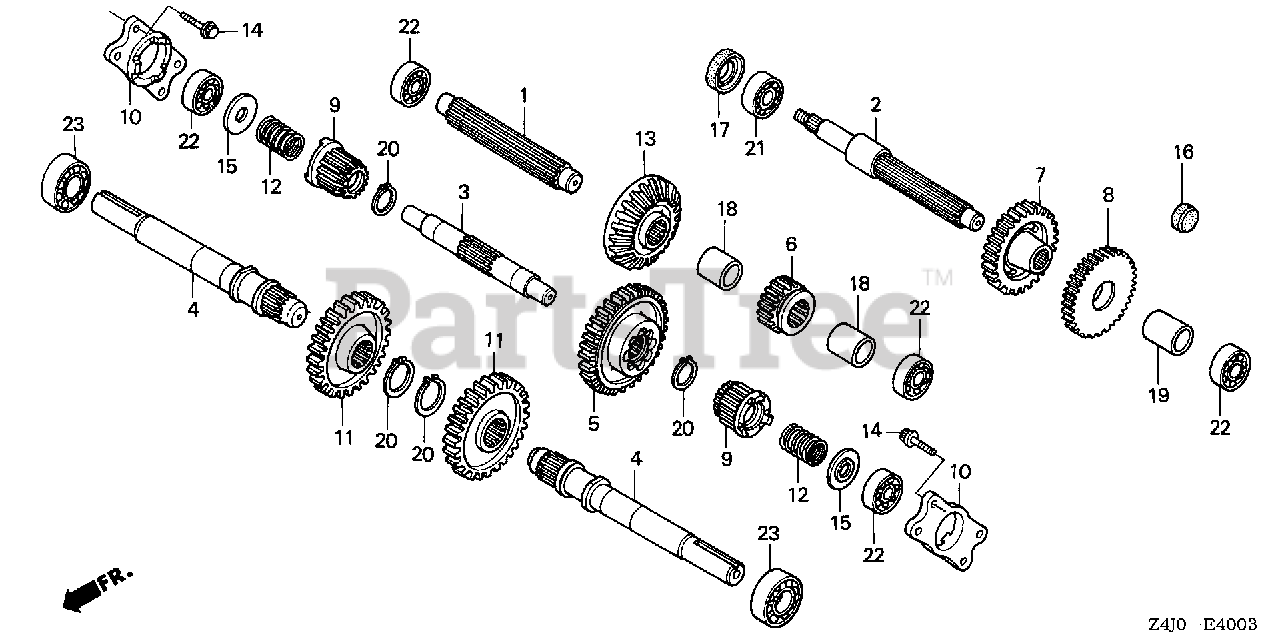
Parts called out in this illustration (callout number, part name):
1	SHAFT, INPUT
2	COUNTERSHAFT
3	SHAFT, SIDE CLUTCH
4	SHAFT, WHEEL
5	GEAR, SIDE CLUTCH DRIVE (49T)
6	GEAR, INPUT SHAFT CHANGE (19T)
7	GEAR, COUNTERSHAFT (36T)
8	GEAR, DRIVEN (42T)
9	GEAR, SIDE CLUTCH (16T)
10	CASE, SIDE CLUTCH BEARING
11	GEAR, FINAL (35T)
12	SPRING, SIDE CLUTCH
13	GEAR, DRIVEN BEVEL (25T)
14	BOLT, SPECIAL (8MM)
15	WASHER, CLUTCH SPRING
16	PLUG, SEALING (28) (ARAI)
17	OIL SEAL (20X31X7) (ARAI)
18	COLLAR (22.3X28.5X37.25)
19	COLLAR (22.3X28.5X43)
20	CIRCLIP (OUTER) (25MM)
21	BEARING, RADIAL BALL (6004)
22	BEARING, RADIAL BALL (6203)
23	BEARING, RADIAL BALL (6205)
